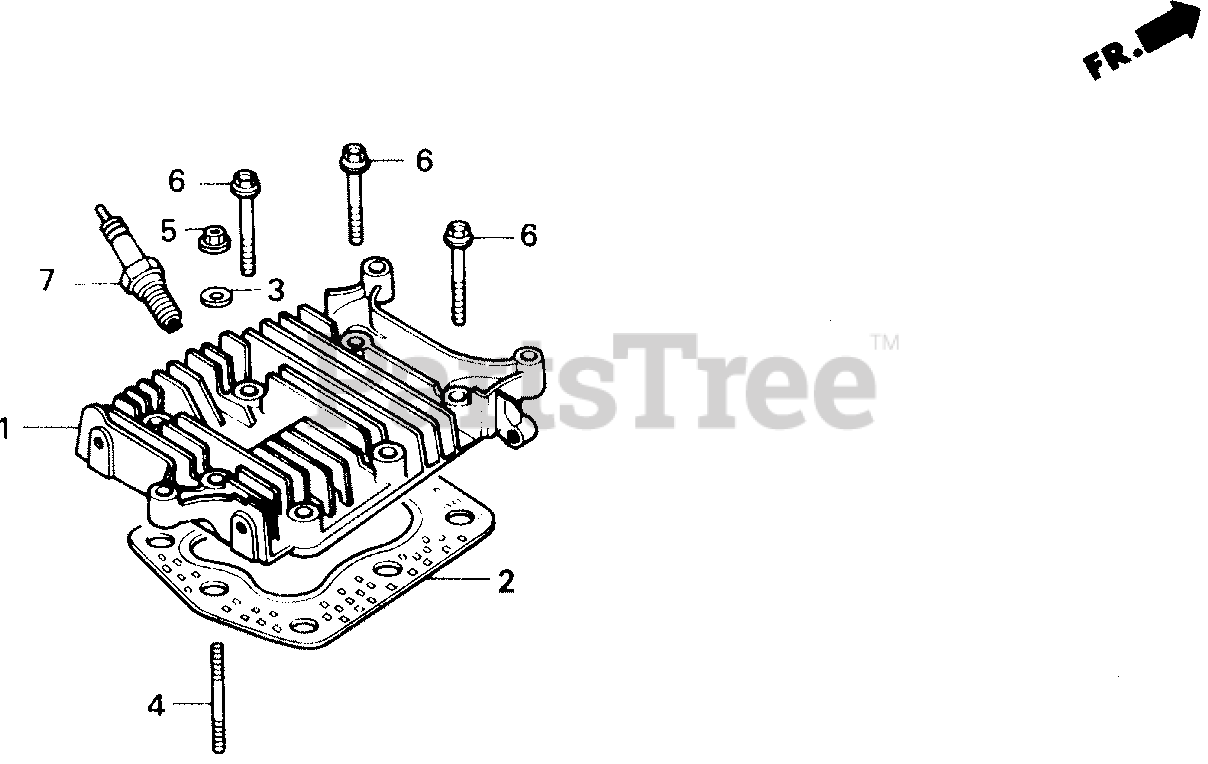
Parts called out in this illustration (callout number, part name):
1	CYLINDER HEAD
2	GASKET, CYLINDER HEAD
3	WASHER (8X22)
4	BOLT, STUD (8X40)
5	NUT-WASHER (8MM)
6	BOLT, FLANGE (8X45)
7	SPARK PLUG (BP-4HS-10) (NGK)
7	SPARK PLUG (BP4HS-10)
7	SPARK PLUG (W14FP-UL10)
